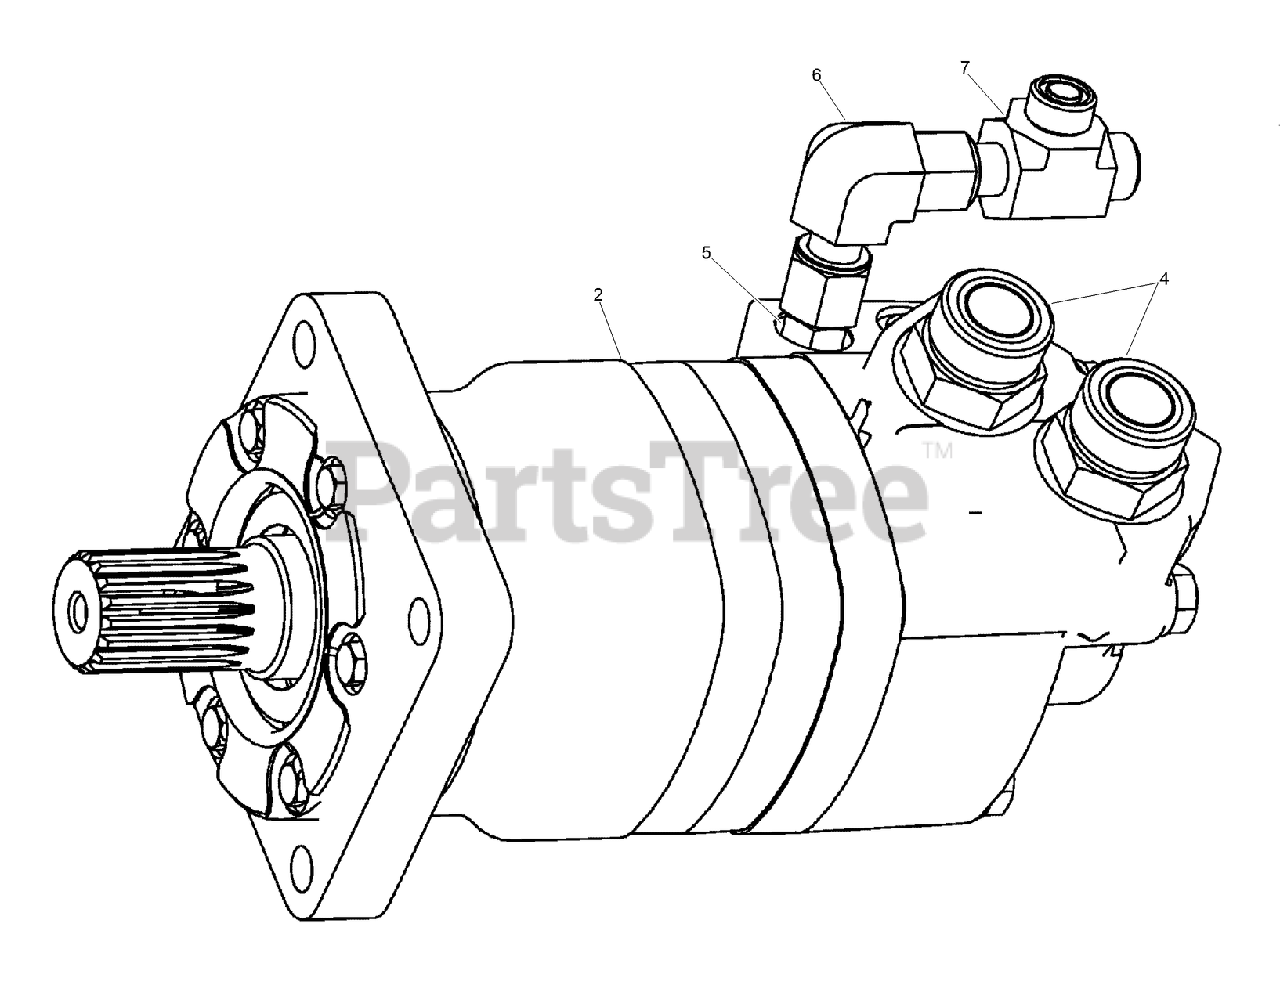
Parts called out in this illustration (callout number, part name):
2	HYD MOTOR ASM
4	CONNECTION - Straight, -16 ORFS / -16 ORB
5	CONNECTION - Straight, -8 ORFS / -6 ORB
6	CONNECTION - 90 Deg, -8 ORFS / -8 ORFS
7	CONNECTION - Run Tee, -8 ORFS / -8 ORFS
